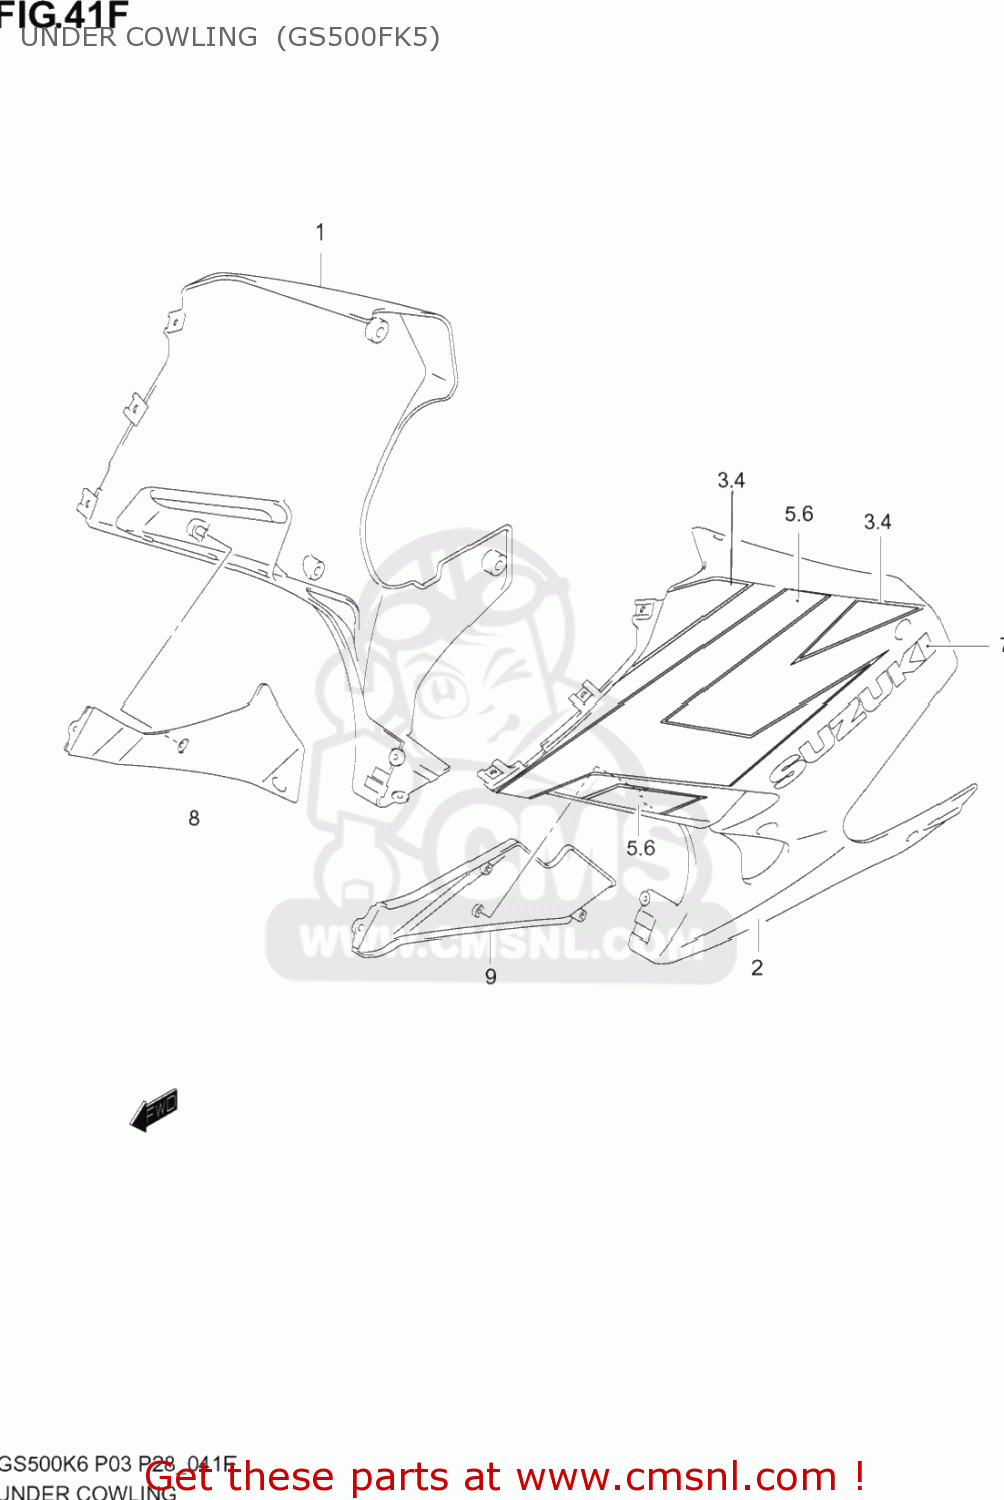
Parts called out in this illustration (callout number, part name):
1	COWL, UNDER RH (WHITE)
2	COWL, UNDER LH (WHITE)
3	TAPE SET RH #1
4	TAPE SET.LH #1
5	TAPE SET,RH #2
6	TAPE SET,LH #2
7	EMBLEM,SUZUKI
8	COWL, INNER RH
9	COWL, INNER LH
10	SHIELD,UNDER C
11	SHIELD,UNDER C
12	SHIELD,UN. HEA
13	SHIELD,UN.HEAT
